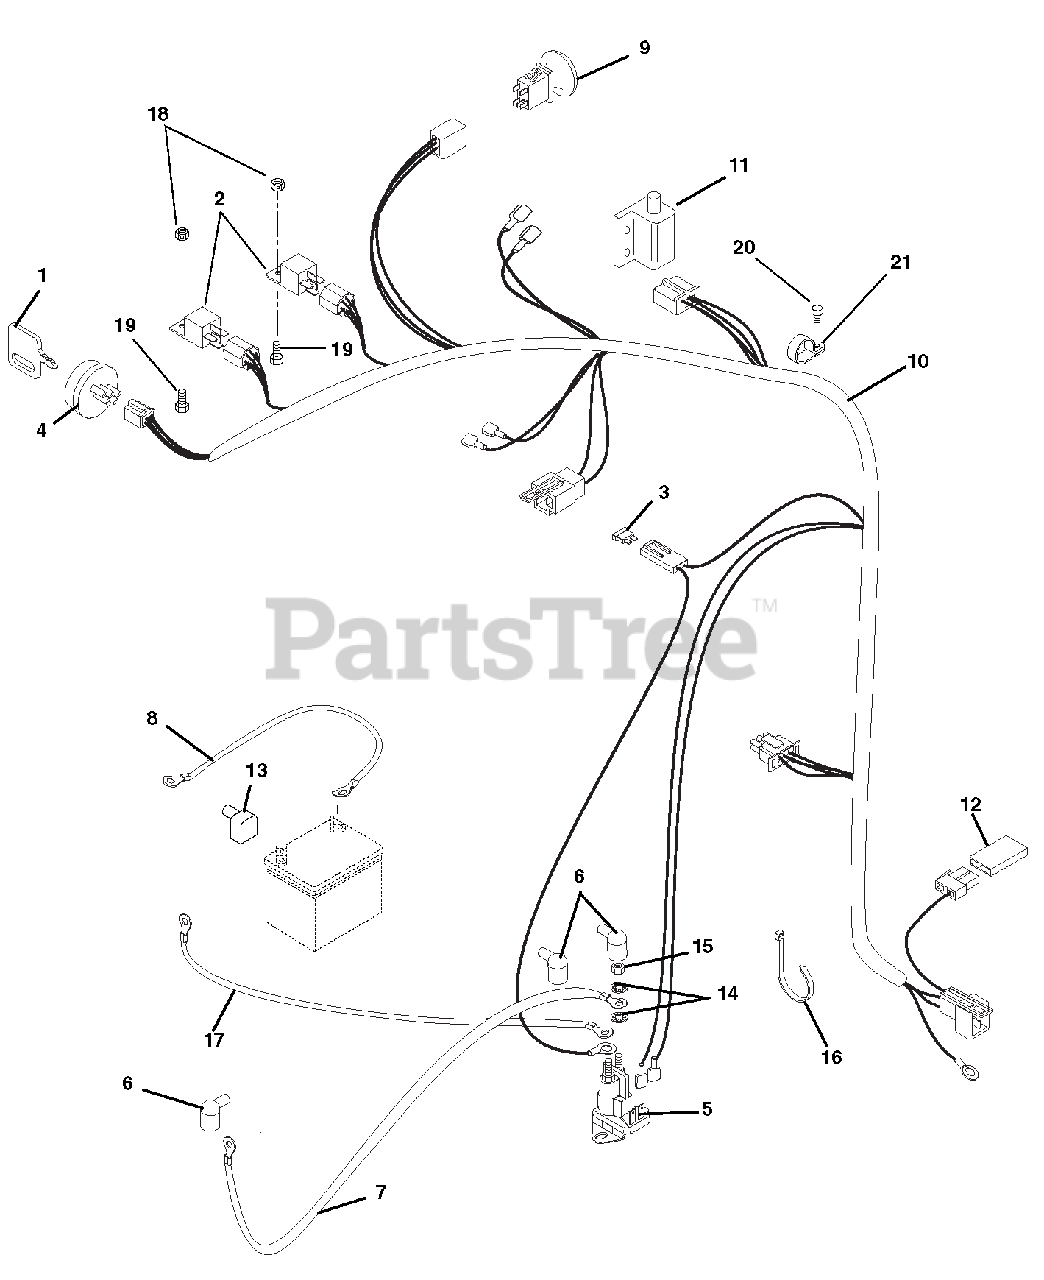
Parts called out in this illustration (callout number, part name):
1	KEY -W/CAP
2	RELAY
3	FUSE-25 AMP ATC TYPE
4	KEY SWITCH
5	SOLENOID, HP RTV
6	BOOT, EYELET TERMINAL
7	STARTER CABLE
8	CABLE-GROUND .25 X 13.00 X .31
9	SWITCH, CLUTCH
10	WIRE HARNESS, XL
11	SWITCH- DOUBLE POLE N.O./N.O.
12	DIODE, CONNECTOR SHELL
13	INSULATOR
14	WSHR-LOCK INT .31 YWZC
15	NUT-JAM .31-24 YWZC
16	CABLE TIE LG 5-1/2
17	POSITIVE CABLE
18	@NUT-LK-NYL 10-24 W/INSRT YWZC
19	@SCR-MCH 10-24X.75 HWH YWZC
20	@SCR-TAP .38-16X.50 HWH TR YWZ
21	CLAMP, CUSHIONED STEEL .75
